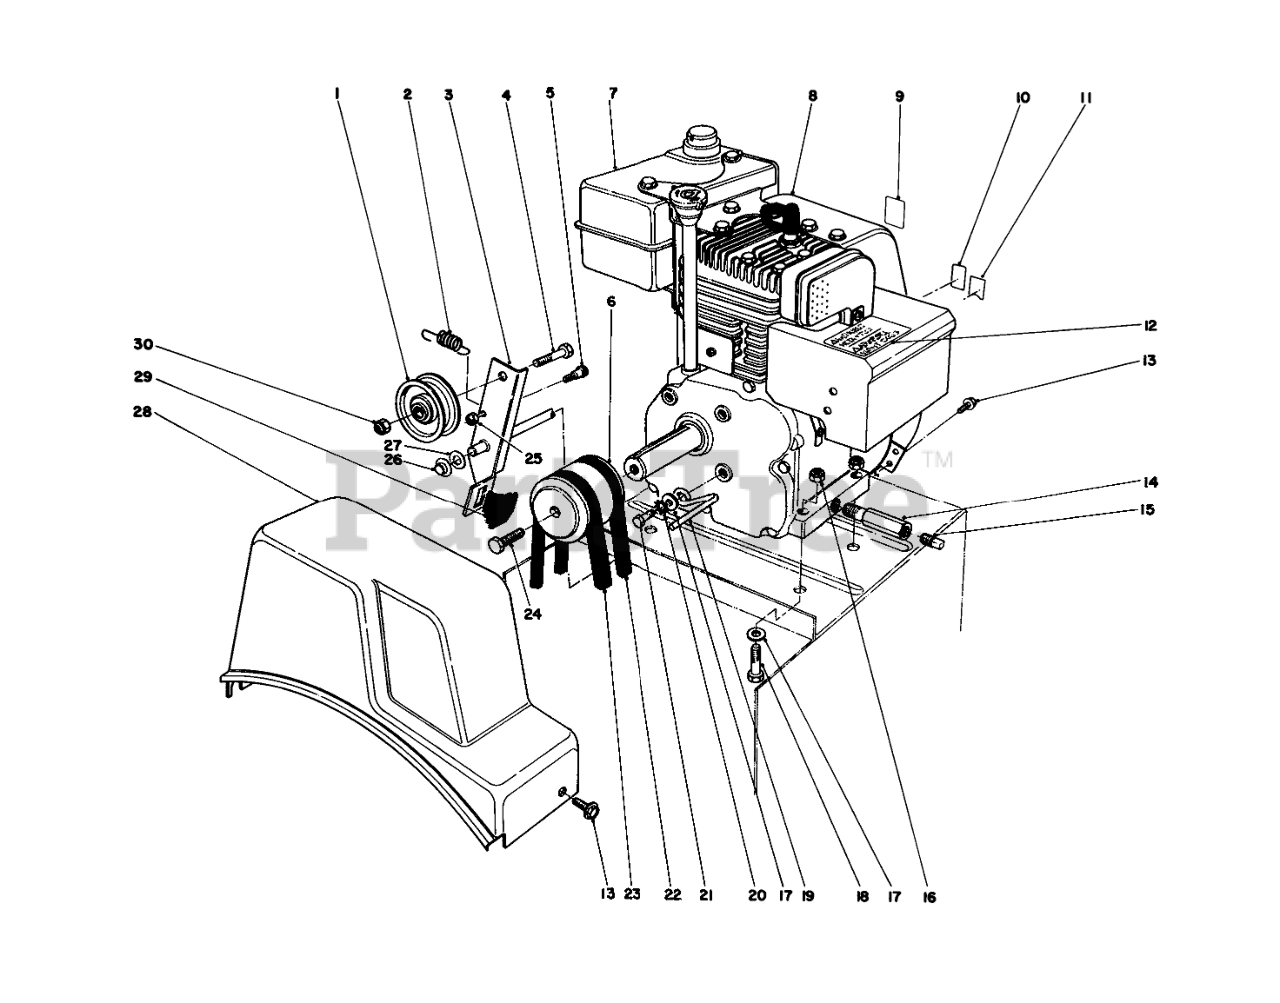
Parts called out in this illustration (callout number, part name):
1	PULLEY-IDLER
2	SPRING
3	Auger Clutch (Incl. Ref. #29)
4	SCREW-HH
5	BOLT-SHOULDER
6	PULLEY-ENGINE
7	GAS TANK 2 QT W CAP
8	Engine
9	PRIMER DECAL
10	DECAL THROTTLE
11	CHOKE DECAL
12	Decal Hot Surface Warning
13	SCREW
14	PIPE-NIPPLE
15	CAP-PIPE
16	NUT-LOCK, NI
17	WASHER-PLAIN
18	SCREW-HH
19	RETAINER-BELT
20	WASHER-LOCK
21	SCREW-HH
22	V BELT-3L, TRACTION
23	V-BELT (29.50 INCH)
24	SCREW-SPECIAL
25	NUT-LOCK, NI
26	RETAINER-PUSH ON
27	WASHER-FLAT
28	COVER-BELT
29	Brake Pad
30	NUT-LOCK, CONE
